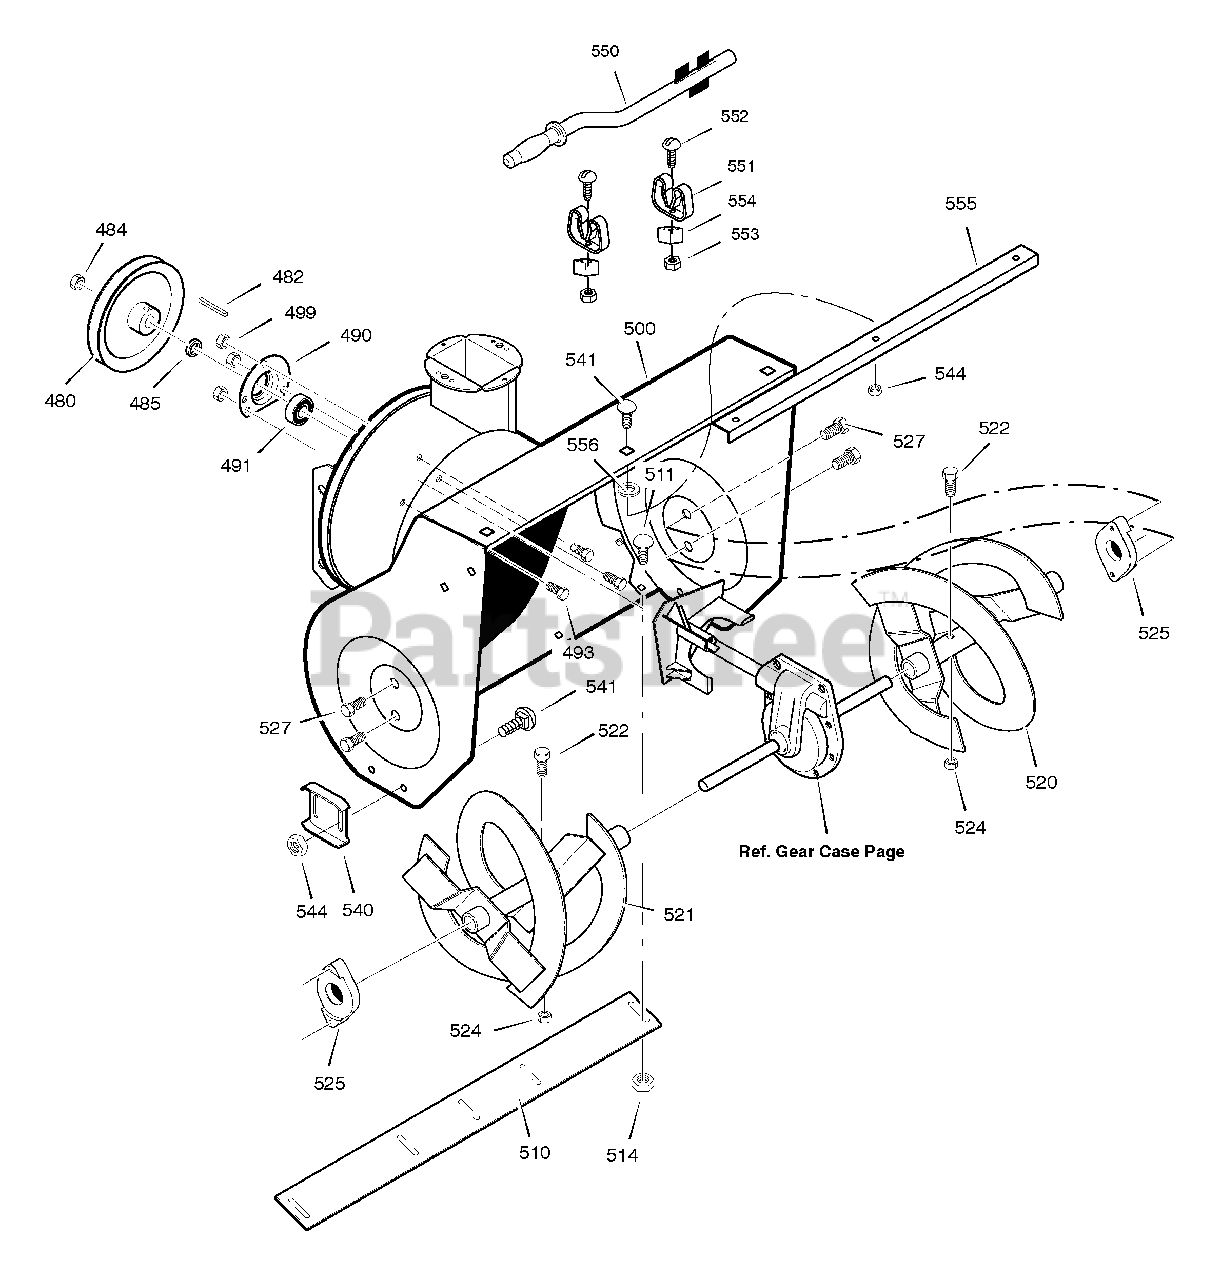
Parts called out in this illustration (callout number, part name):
480	PULLEY, 4L 8.40 OD
482	KEY, SQUARE 3/16 X 3/4
484	NUT, 1/2-20
485	SPACER, FRICTION PULLEY
490	RETAINER, BALL BRNG
491	BEARING, BALL
493	BOLT, HEX 5/16-18X 0.62
499	NUT, 5/16-18 HEXWDFLLK
500	HOUSING, ASSY
510	BLADE, SCRAPER
511	BOLT, 5/16-18x0.62
514	NUT, 5/16-18
520	AUGER, ASSY, LH
521	AUGER, ASSY, RH
522	SCREW, 5/16
524	NUT, 5/16
525	BEARING, FLANGE
527	SCREW, 5/16-18 x 0.75
540	SKID, HEIGHT ADJUST
541	BOLT, 5/16-18 X 0.75
544	NUT, 5/16-18
550	BRUSH, CLEANOUT
551	CLIP, RETAINER
552	SCREW
553	NUT
555	STIFFENER
556	WASHER
